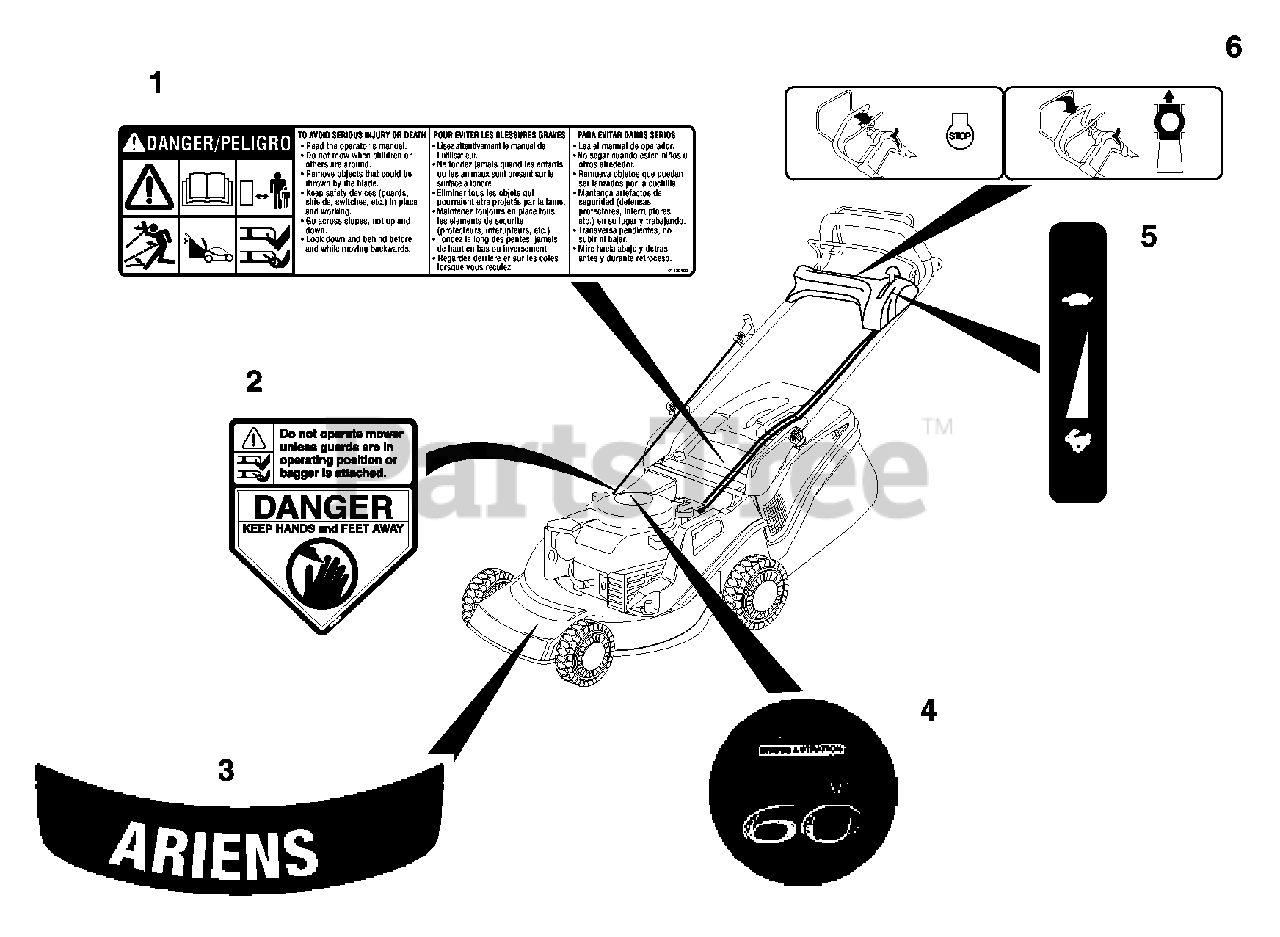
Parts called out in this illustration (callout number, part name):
1	DECAL, DANGER
2	DECAL, CPSC DANGER
3	DECAL, ARIENS 21" DECK
4	DECAL, ENGINE B&S QUANTUM 6.0
5	DECAL, THROTTLE
6	DECAL, CONTROL SELF-PROP
